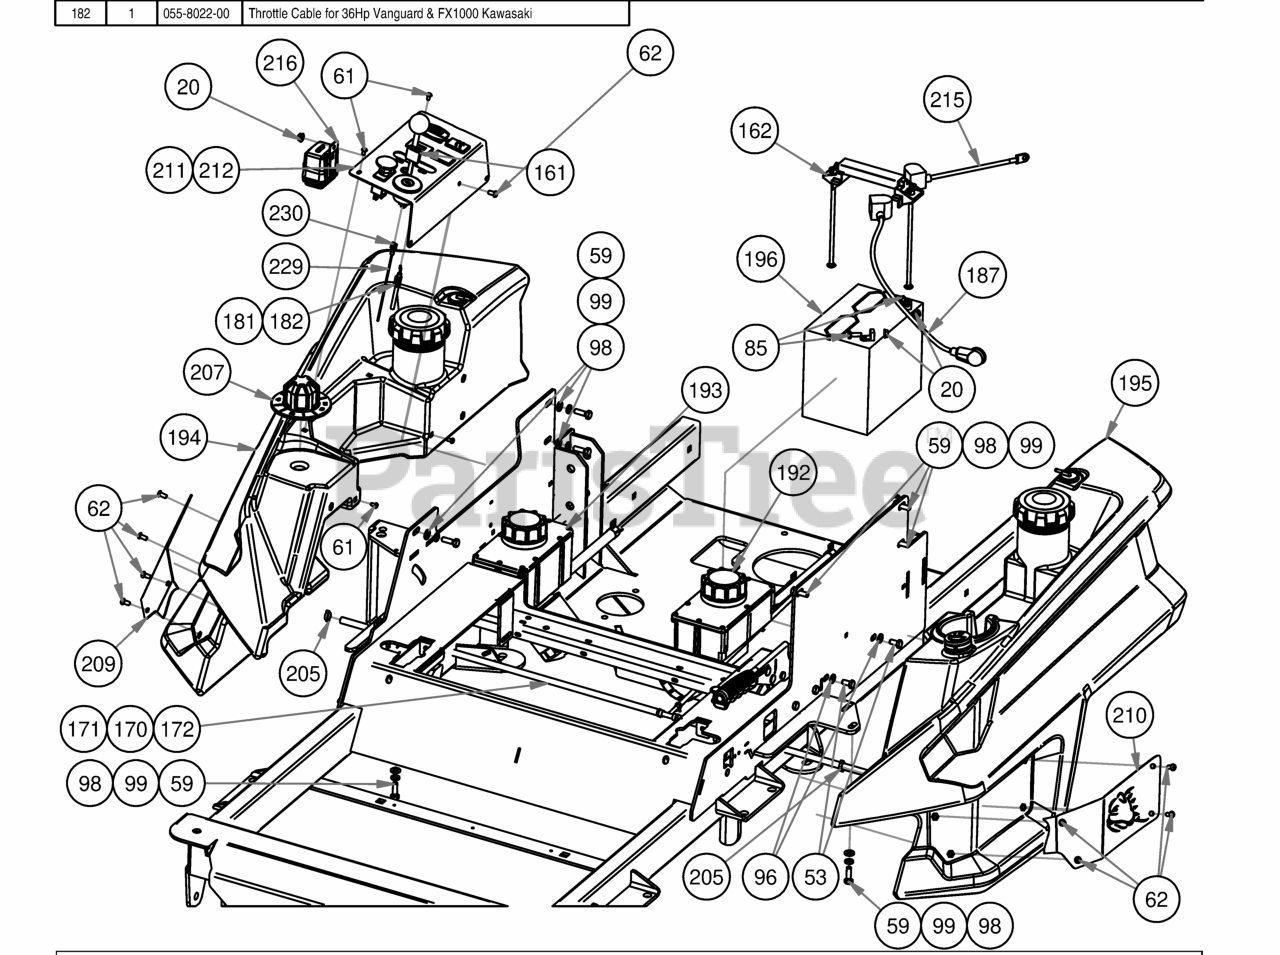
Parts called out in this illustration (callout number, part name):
20	1/4-20 Hex Flange Nuts Zinc w/Serrations
53	5/16-18 x 5/8 Hex Bolt
59	5/16" x 1" Bolt
61	10-32 x 3/8" Button Socket Head Bolt
62	1/4" x 1/2" BS C/S 18-8 SS
85	1/4" x 3/4" Hex Bolt
96	1/4" Flat Washer
98	5/16" Flat Washer
99	5/16" Lock Washer
161	Ignition Key
162	Hold Down Assembly
170	2019 Rebel Rogue Renegade Fuel Line for Vanguard & Yamaha
171	2019 Rebel Rogue Renegade Fuel Line for Kohler
172	2019 Rebel Rogue Renegade Fuel Line for Kawasaki
181	Outlaw Throttle Cable
182	Throttle Cable for 36Hp Vanguard & FX1000 Kawasaki
187	24" Red Battery Cable
192	LH Rogue Hydro Tank Assy
193	RH Rogue Hydro Tank Assy
194	2019 Right Rebel, Rogue, Renagade Fuel Tank (GAS)
195	2019 Left Rebel, Rogue, Renegade Fuel Tank (GAS)
203	2019 Veritical Suspension Frame
205	2 EAR CLAMP 12.5mm-15mm
207	2019 Deck Height Dial
209	2019 Outlaw Fuel Tank Insert - Right
210	2019 Outlaw Fuel Tank Insert - Left
211	Rebel/Rogue EFI Control Panel Assy
212	Rebel/Rogue Control Panel Assy
215	Starter Cable
216	2019 Wiring Harness-Rebel/Rogue
229	16 AWG Black Insulated Wire for Tachometer
230	1/4" Female Quick Connect Terminal
